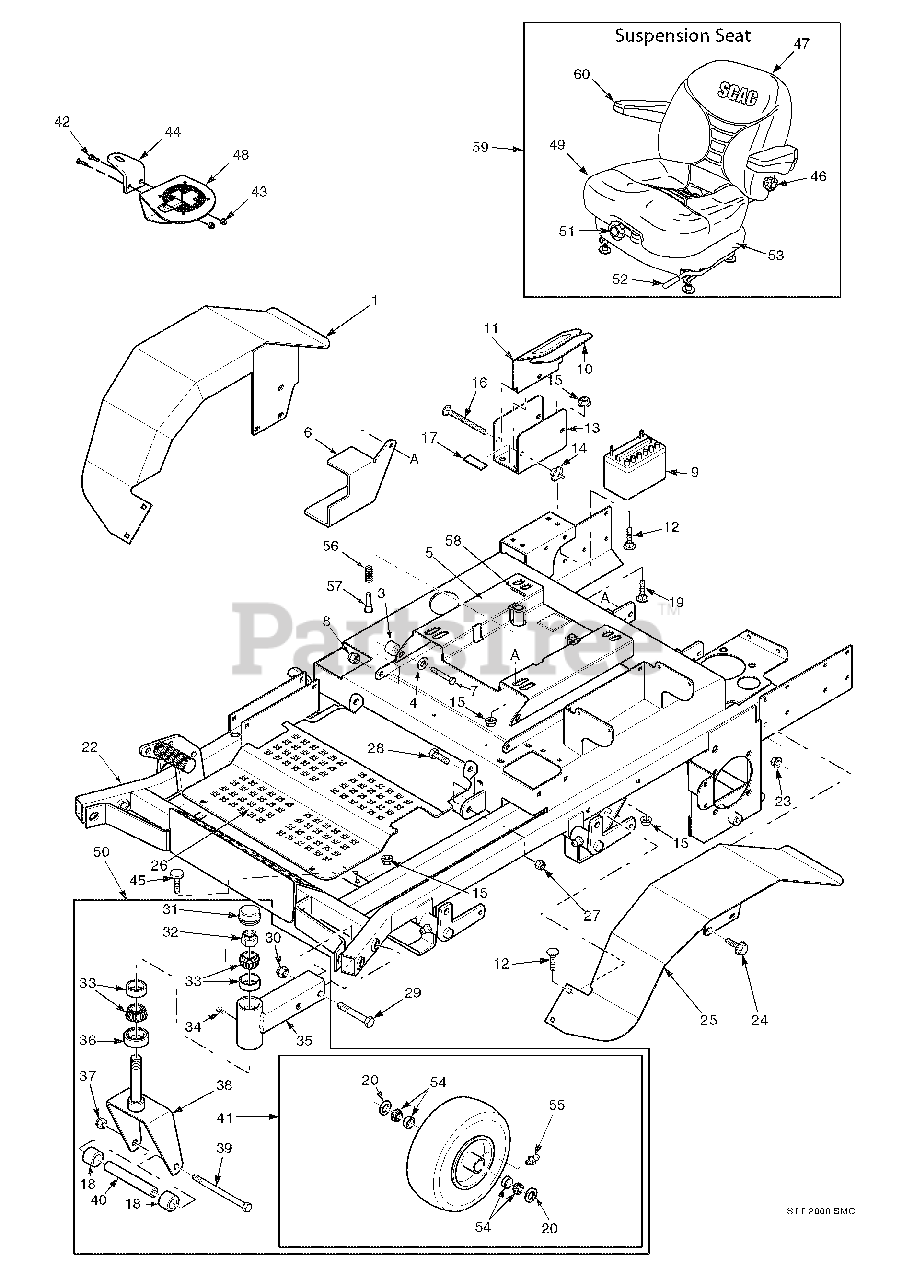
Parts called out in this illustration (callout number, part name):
1	Fender Weldment, RH
2	Bolt, Hex Head, 5/16-18 x 1, Zinc
3	Spacer
4	Flatwasher, 3/8-.391 x .938 x .105
5	Seat Plate Weldment
6	Guard, Fuel Line
7	Bolt, Hex Head 3/8-16 x 2.0"
8	Nut, Elastic Stop 3/8-16
9	Battery
10	Pad, Battery Cover
11	Cover, Battery
12	Bolt, Carriage 5/16-18 x 3/4"
13	Plate, Battery Box
14	Wing Nut, 1/4-20 x 3/4"
15	Nut, Hex Serrated Flange 5/16-18
16	Bolt, Carriage 1/4-20 x 6"
17	Rubber Pad
18	Spacer, Caster Wheel
19	Bolt, Carriage 5/16-18 x 1"
21	Lock Nut, 3/8-16, Elast. Stop
22	Main Frame
23	Nut, Hex Serrated Flange 3/8-16
24	Screw, Hex Serrated Flange 3/8-16 x 1"
25	Fender Weldment, LH
26	Foot Plate
27	Nut, Hex Elastic Stop 3/8-16
28	Bolt, Hex Head 3/8-16 x 1"
29	Bolt, Hex Head 5/8-11 x 4"
30	Nut, Hex Elastic Stop 5/8-11
31	Cap, Grease
32	Nut, Hex Elastic Stop 1.0-14
33	Bearing W/Race
34	Plug, 1/4-28 THD Form
35	Extention Weldment, Caster 61V
36	Seal, 2.00 OD. x 1.625 Bore
37	Nut, Hex Elastic Stop 1/2-13
38	Yoke Weldment, Caster
39	Bolt, Hex Head 1/2-13 x 9-1/2"
40	Sleeve, Caster Wheel
41	Wheel Assy, 61V, 72A
42	Bolt, Hex Head 1/4-20 x 3/4"
43	Bolt, Hex Head 1/4-20 x 3/4"
44	Mounting Bracket, STT Cup Holder
45	Lumbar Kit
46	Cable, Seat Stop
47	Back Cushion Kit
48	Cup Holder Assembly
49	Seat Cushion Kit Seat Drain Kit
50	Caster Wheel Assy 61V
51	Weight Adjustment Kit
52	Seat Adjustment, Track Set
53	Shock Absorber Kit
54	Bearing w/ Race
55	Grease Fitting
56	Spring, Seat
57	Pin Retainer, Spring
58	Roll Pin, Spring 5/32 x 3/4"
59	Suspension Seat Assembly w/seat belt
60	Armrest Only
